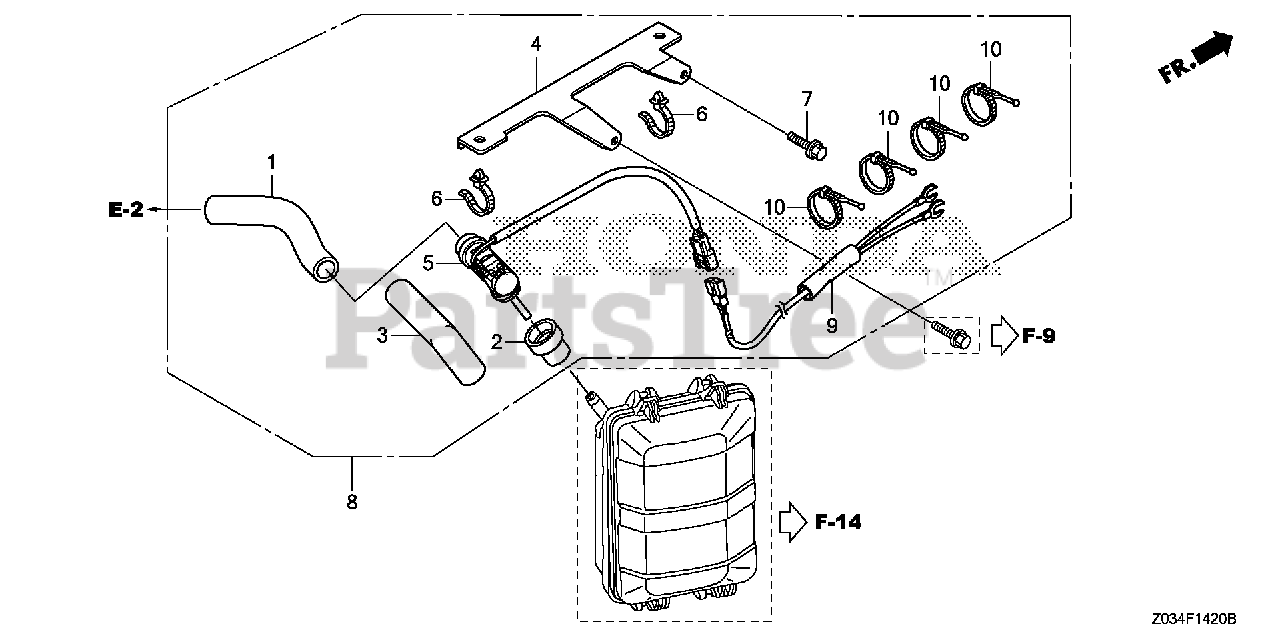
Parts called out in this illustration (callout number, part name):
1	TUBE A, BREATHER
2	TUBE B, BREATHER
3	INSULATOR L, BREATHER TUBE
4	BRACKET, WIRE HARNESS CLIP
5	HEATER ASSY., BREATHER
6	CLIP, HARNESS BAND (151.5MM) (NATURAL)
7	BOLT, FLANGE (6X12) (CT200)
8	HEATER KIT, BREATHER
9	SUB-WIRE ASSY.
10	TIE, CABLE (NATURAL 154X3.4)
